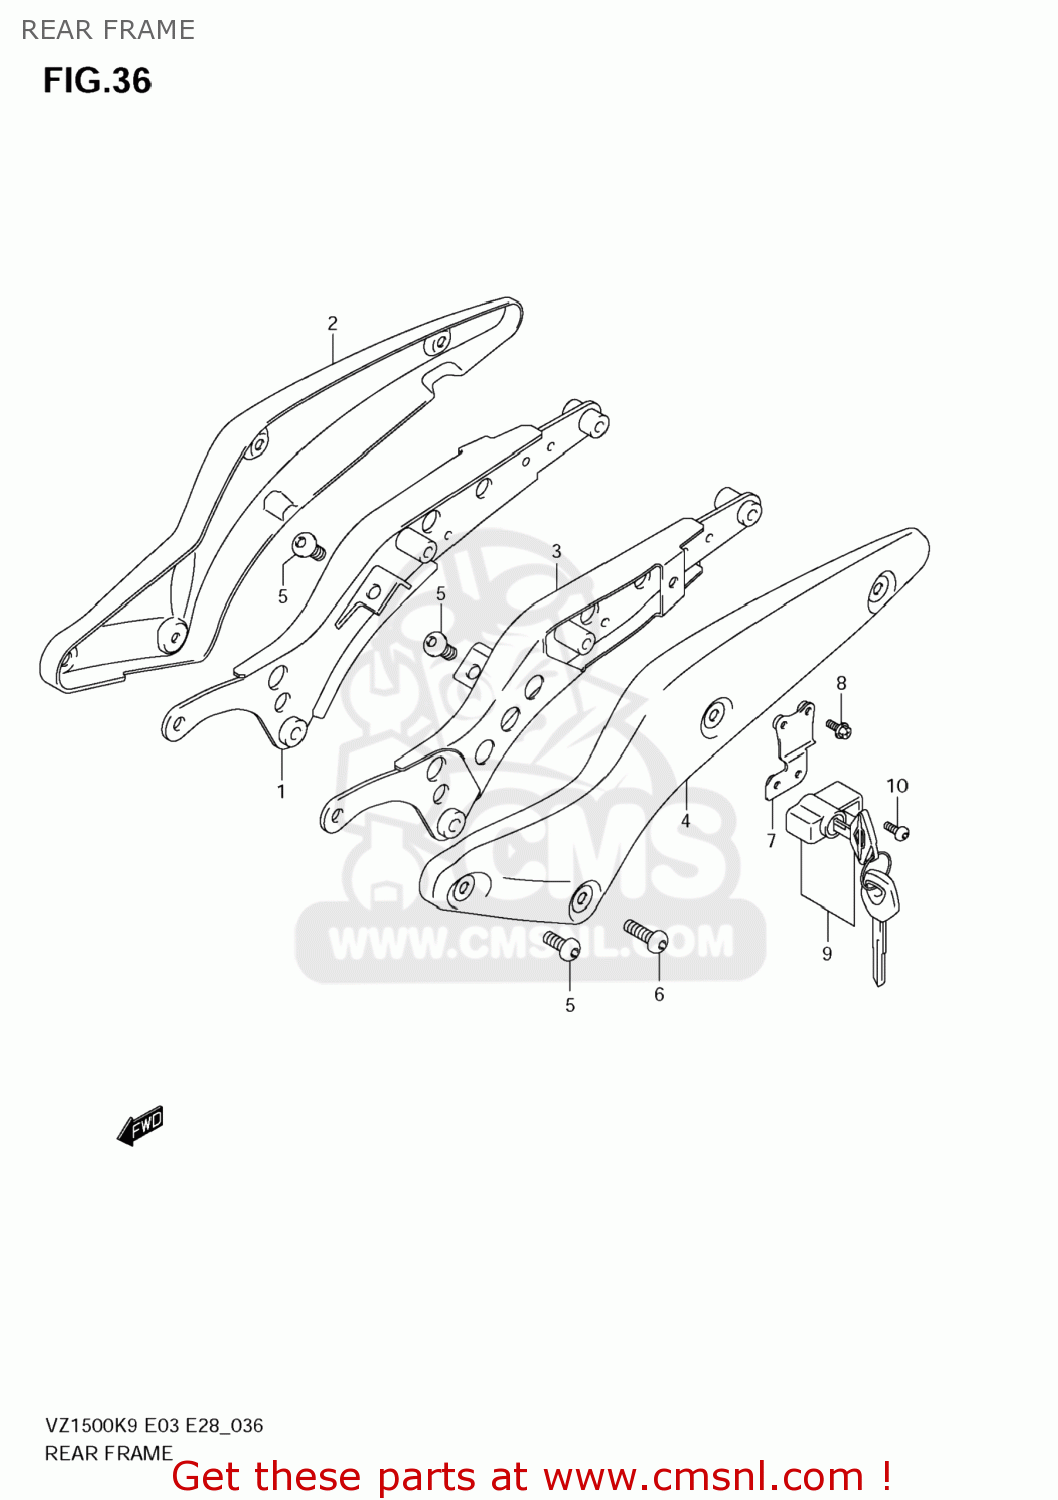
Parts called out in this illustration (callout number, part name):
1	FRAME,RR,R
2	PLATE,RR FRAME,R
3	FRAME,RR,L
4	PLATE,RR FRAME,L
5	BOLT(10X25)
6	BOLT(10X35)
7	BRACKET,HELMET LOCK
8	SCREW
9	LOCK SET,HELMET
10	SCREW(6X14)
